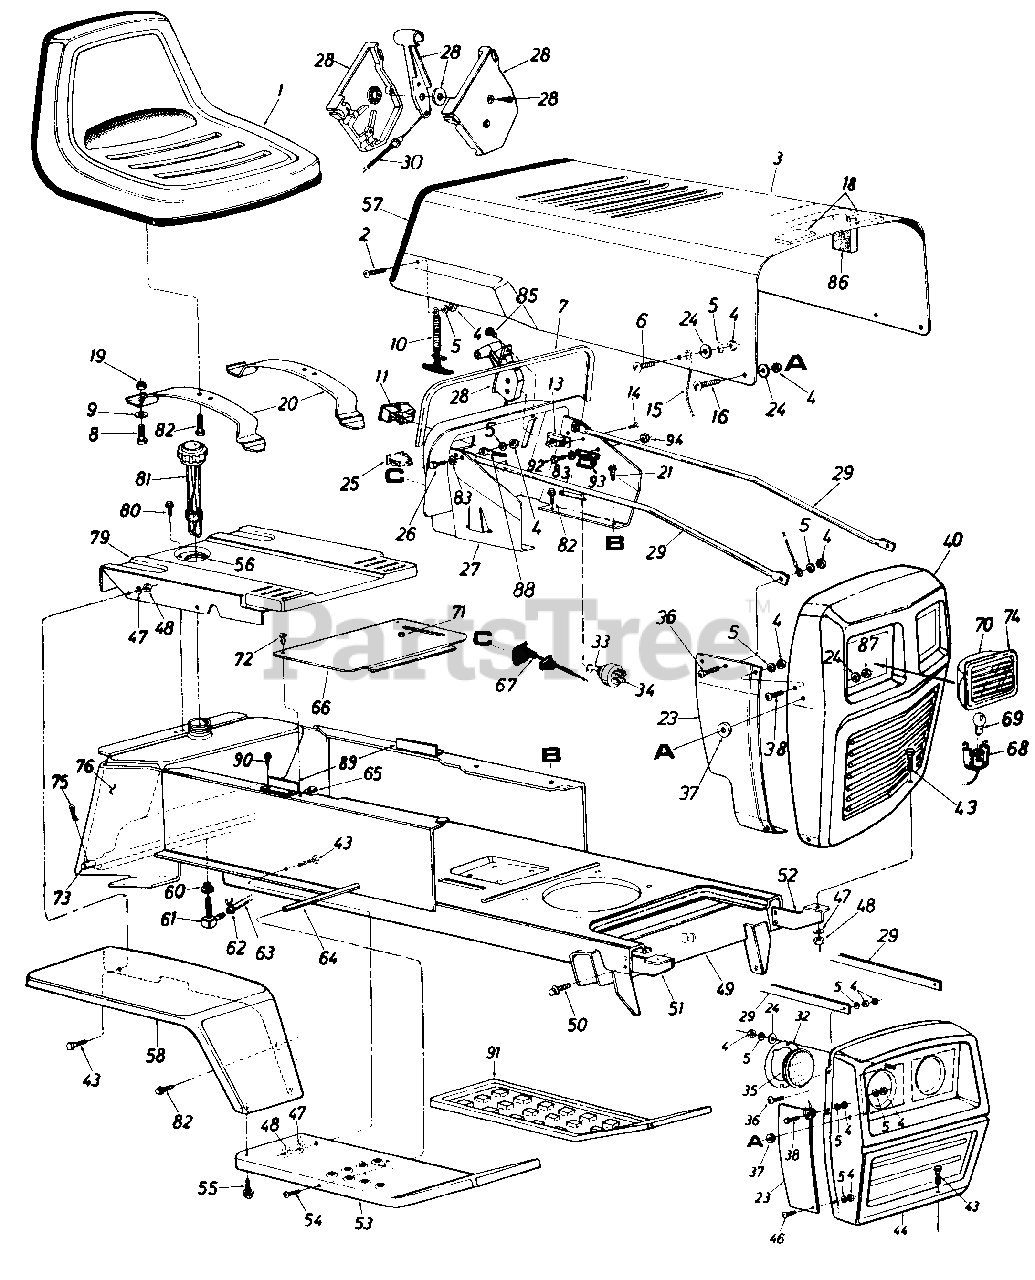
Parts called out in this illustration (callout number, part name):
1	Seat Assembly
2	Truss Mach. Scr. 1/4-20 x .50" Lg.
5	L-Wash. 1/4" I.D.
6	Truss Mach. Scr. 1/4-20 x .50" Lg.
7	Vinyl Molding Strip 29"
8	Hex Nylon Scr. 1/2-13 x .75" Lg.
9	Fl-Wash 50" I.D. x 1.00"O D x .090
10	Hood Latch Ass'y.
11	Ammeter
13	Circuit Breaker 8 Amp.
14	Hex Tap Scr. #10 x .50"
15	Hood Stop
16	Truss Mach. Scr. 1/4-20 x .75" Lg.
18	PVC Foam Strip
19	Hex Nut 1/2-13Thd.*
23	Grille Side Panel R.H.
24	Fl-Wash. 1/4" I.D.
25	Light Switch
26	Truss Hd. Scr. 1/4-20 x 1"
27	Dash Panel Ass'y.
28	Throttle Control Box Comp.
29	Grille Positioning Rod
30	Throttle Control Cable
32	Head Lamp Retainer
33	Ignition Key
34	Ignition Switch
35	Head Lamp
36	Truss Machine Scr. 1/4-20 x .75" Lg.
37	Rubber Washer
38	Truss Mach. Scr. 1/4-20 x .50" Lg.*
44	Grille Round Headlights
46	Truss Mach. Scr. 1/4-20 x .50" Lg.
47	L-Wash. 5/16" I.D.
48	Hex Nut 5/16-18 Thd.
49	N Lower Frame Ass'y.
50	Hex Thd. Rolling Scr. 5/16n x.75" Lg.
51	Grille Mount Brkt. R.H.
52	Grille Mount Brkt. L.H.
55	Hex Thd. Rolling Scr. 5/16-24 x .75" Lg.
56	Grommet
57	Vinyl Moulding Strip 31"
61	90ø Nipple
62	Hose Clamp
63	Gas Line 46" Lg.
64	Running Board Rod
65	Speed Nut #10-24
66	Transmission Cover Ass'y.
67	Choke Control Comp.
68	Socket
69	Lamp
70	Headlight Housing
71	Snap Bushing
72	Truss Hd. Scr. #10 x .50"
73	Hitch Rod
74	Lens
75	Internal Cotter Pin
76	Gas Tank
79	Seat Plate
80	Hex Thd. Rolling Scr. 5/16-24 x .75" Lg.
81	Gas Gauge
82	Hex Thd. Rolling Scr. 5/16-24 x .75" Lg.
83	External Wash. 1/4" I.D.
85	Truss Mach. AB-Tap Scr. #10 x .50" Lg.
86	PVC Foam Strip
87	Hex L-Nut 1/4-20 Thd.
88	Ground Wire
89	Seat Spring Guide
90	Hex AB-Tap Scr. 1/4 x .625"
91	Foot Pad
92	Hex Bolt 1/4-20 x .5" Lg.
93	Solenoid
94	Hex Sems Nut 1/4-20 Thd.
